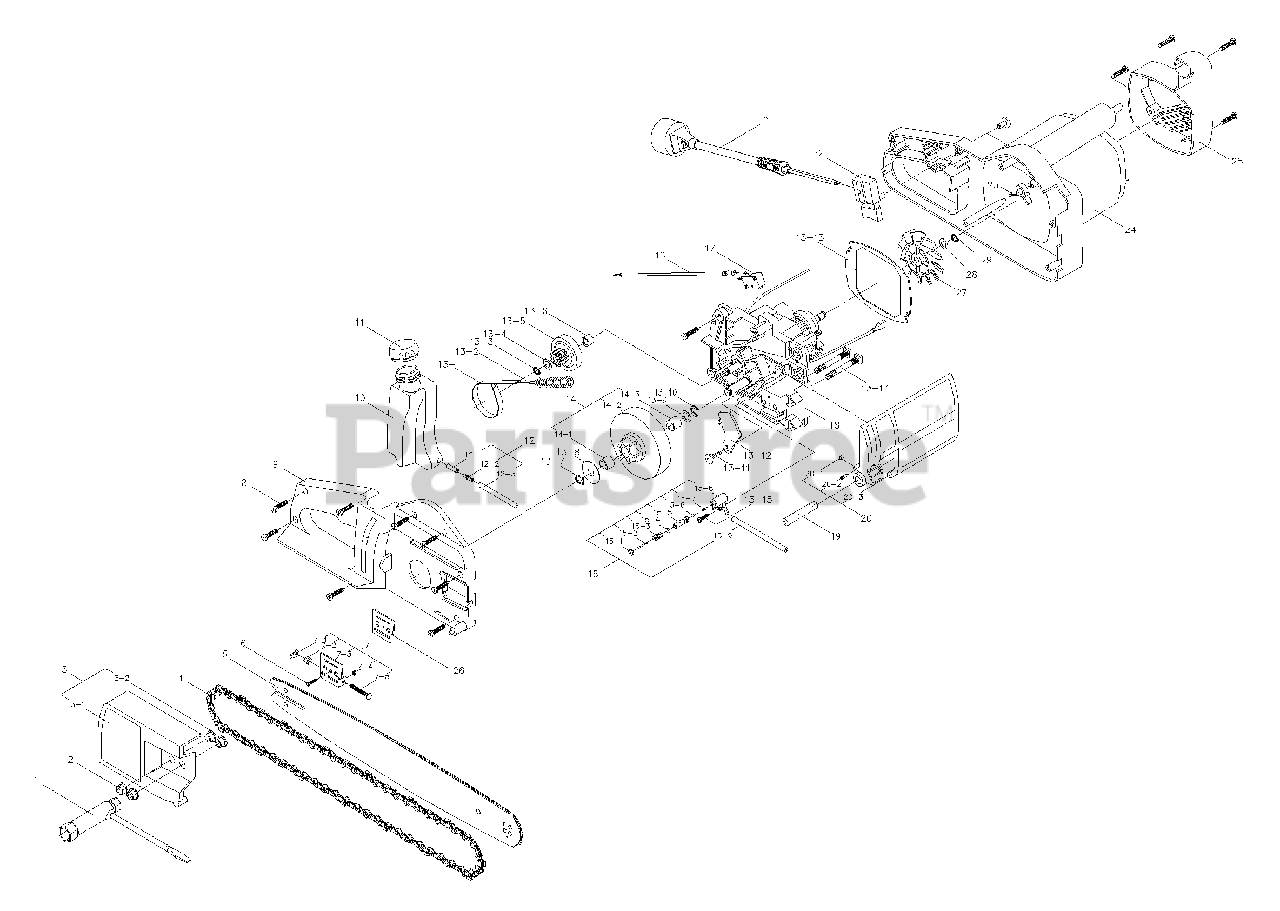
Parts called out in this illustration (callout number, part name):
3	CHAIN COVER ASS'Y
4	16" CHAIN
7	BAR ADJUSTMENT ASS'Y
9	HOUSING (R)
10	LUBRICANT TANK (FOR CHAIN)
11	TANK'S COVER
12	PIPE ASS'Y
13	TRANSMISSION ASS'Y
14	INNER GEAR ASS'Y
15	LUBRICANT PUMP ASS'Y
16	CONDUIT ASS'Y
17	MICRO-SWITCH
19	BRAKE'S SHAFT
20	BRAKE'S POLE ASS'Y
21	POWER CORD
22	SWITCH
23	POLE FOR BRAKE'S MICRO-SWITCH
24	HOUSING (L)
25	REAR COVER
26	OIL WASHER
